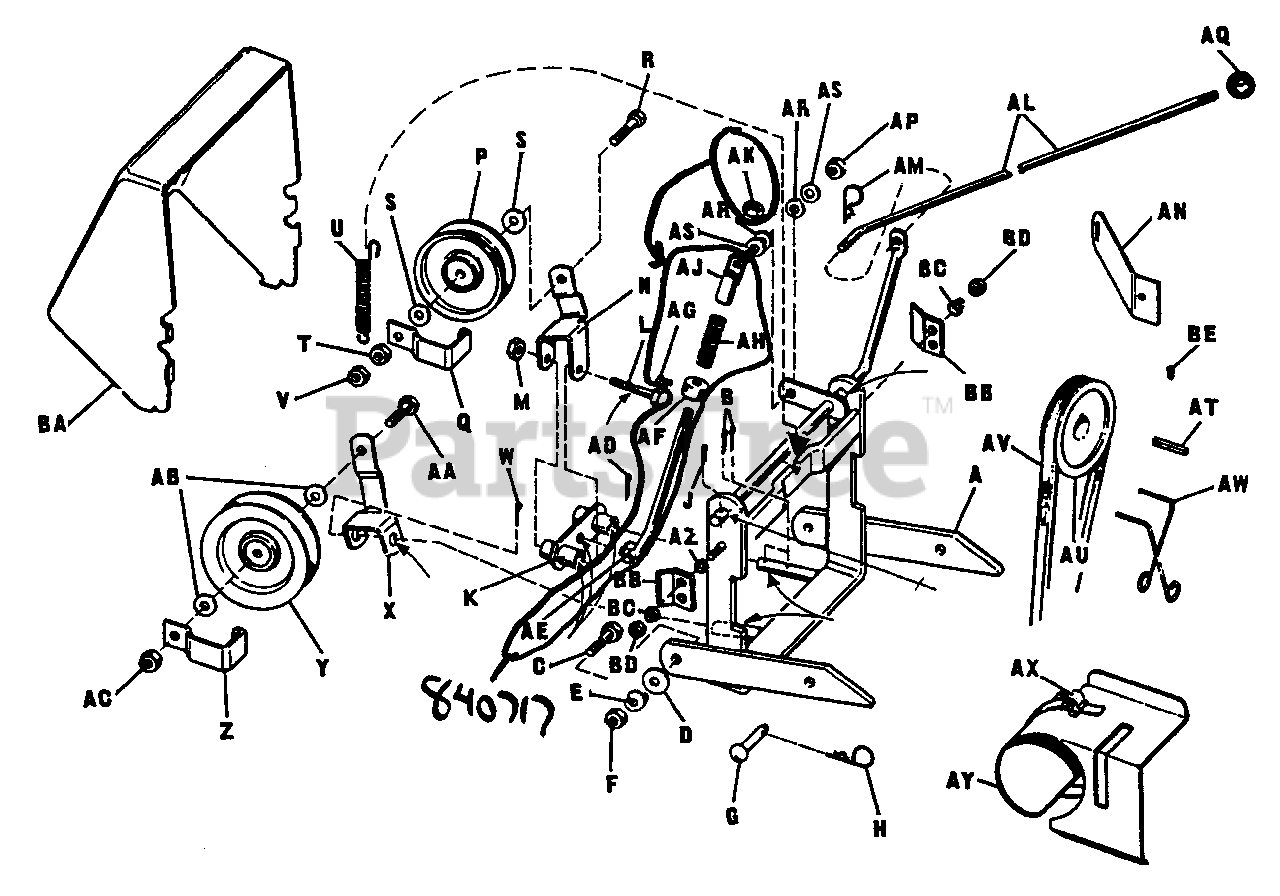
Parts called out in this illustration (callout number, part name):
A	Hitch Assembly
B	Cotter Pin, 1/8" Dia. x 1"
C	Hex. Cap Screw
D	Plain Washer, 3/8"
E	Spring Washer, 3/8"
F	Full Lock Hex Nut, 3/8"-24
G	Pin
H	Spring Clip
J	Cotter Pin, 1/8" Dia. x 1"
K	Lever Ass'y Idler
L	Hex. Cap Screw
M	Full Lock Hex. Nut, 3/8"-16
N	Idler Bracket
P	Idler Pulley
Q	Guide Belt
R	Hex. Cap Screw, 3/8"-16 x 1-1/2"
S	Plain Washer, 5/16"
T	Hex. Jam Nut
U	Return Spring
V	Full Lock Nut, Hex. 3/8"-16
W	Cotter Pin, 1/8" Dia. x 1"
X	Idler Bracket
Y	Idler Pulley
Z	Belt Guide
AA	Hex. Cap Screw, 3/8"-16 x 1-1/4"
AB	Plain Washer, 5/16"
AC	Full Lock Nut, Hex. 3/8"-16
AD	Cotter Pin, 3/32" Dia. x 3/4"
AE	Clutch Rod
AG	Set Sq. Hd. Cup Pt. Screw, 1/4"-20 x 3/8" lg.
AJ	Rod Assembly Guide
AK	Hex. Full Lock Nut, 5/16"-18
AL	Clutch Handle
AM	Spring Clip
AP	Nut, Stop, 5/16"-18
AR	Nylon Washer
AS	Plain Washer, 5/16"
AU	Engine Pulley
AX	Deflector Clamp
AY	Heat Deflector
BA	Cover, Pulley
BB	Clip, Pulley Cover
BC	Spring, Concial
BD	Hex. Full Lock Nut, 5/16"-18
BE	Set Screw
